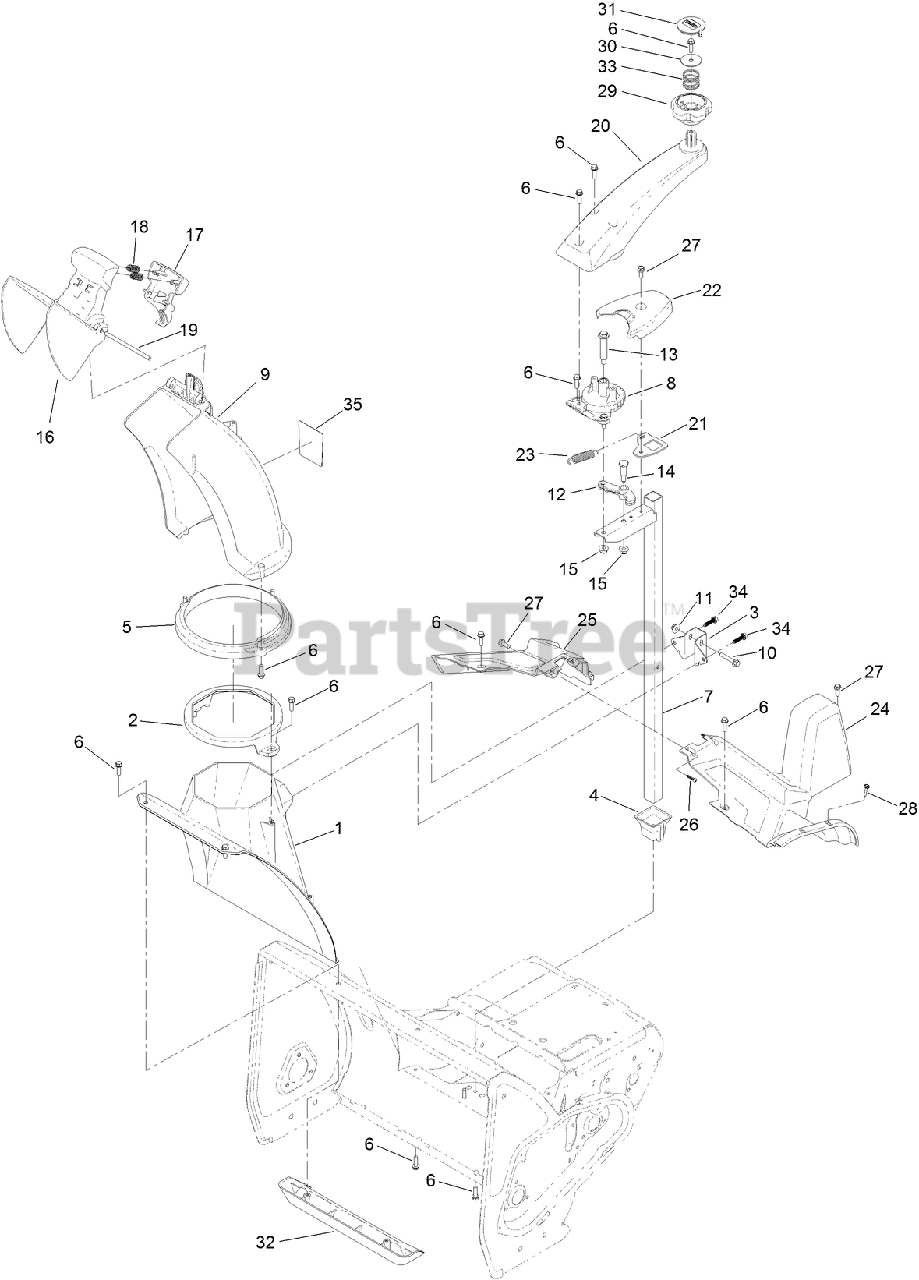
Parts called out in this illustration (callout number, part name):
1	CHUTE-LOWER
2	GUIDE-CHUTE
3	BRACKET-POST, SUPPORT (CHUTE)
4	RETAINER- POST, CHUTE
5	RING-CHUTE
6	SCREW-HWH
7	POST-CHUTE, MANUAL
8	GEAR-CHUTE, MANUAL
9	CHUTE-DISCHARGE
10	SCREW-HHF
11	NUT-HF
12	LATCH-CHUTE
13	BOLT-SHOULDER
14	SCREW-SHOULDER
15	NUT-HF, NI
16	DEFLECTOR-CHUTE
17	TRIGGER-DEFLECTOR
20	HANDLE-CHUTE, MANUAL
21	SUPPORT-SPRING
22	COVER-SPRING
23	SPRING-EXTENSION
24	SHROUD-UPPER, LH
25	SHROUD-LOWER, RH
26	SCREW-PPH
27	SCREW-HWH
28	SCREW-HWH
29	KNOB-CONTROL, CHUTE
30	WASHER-FLAT
31	INSERT-KNOB
32	KICKER-HOUSING
33	SPRING-COMPRESSION
34	SCREW-FLANGE, PLASTIC
